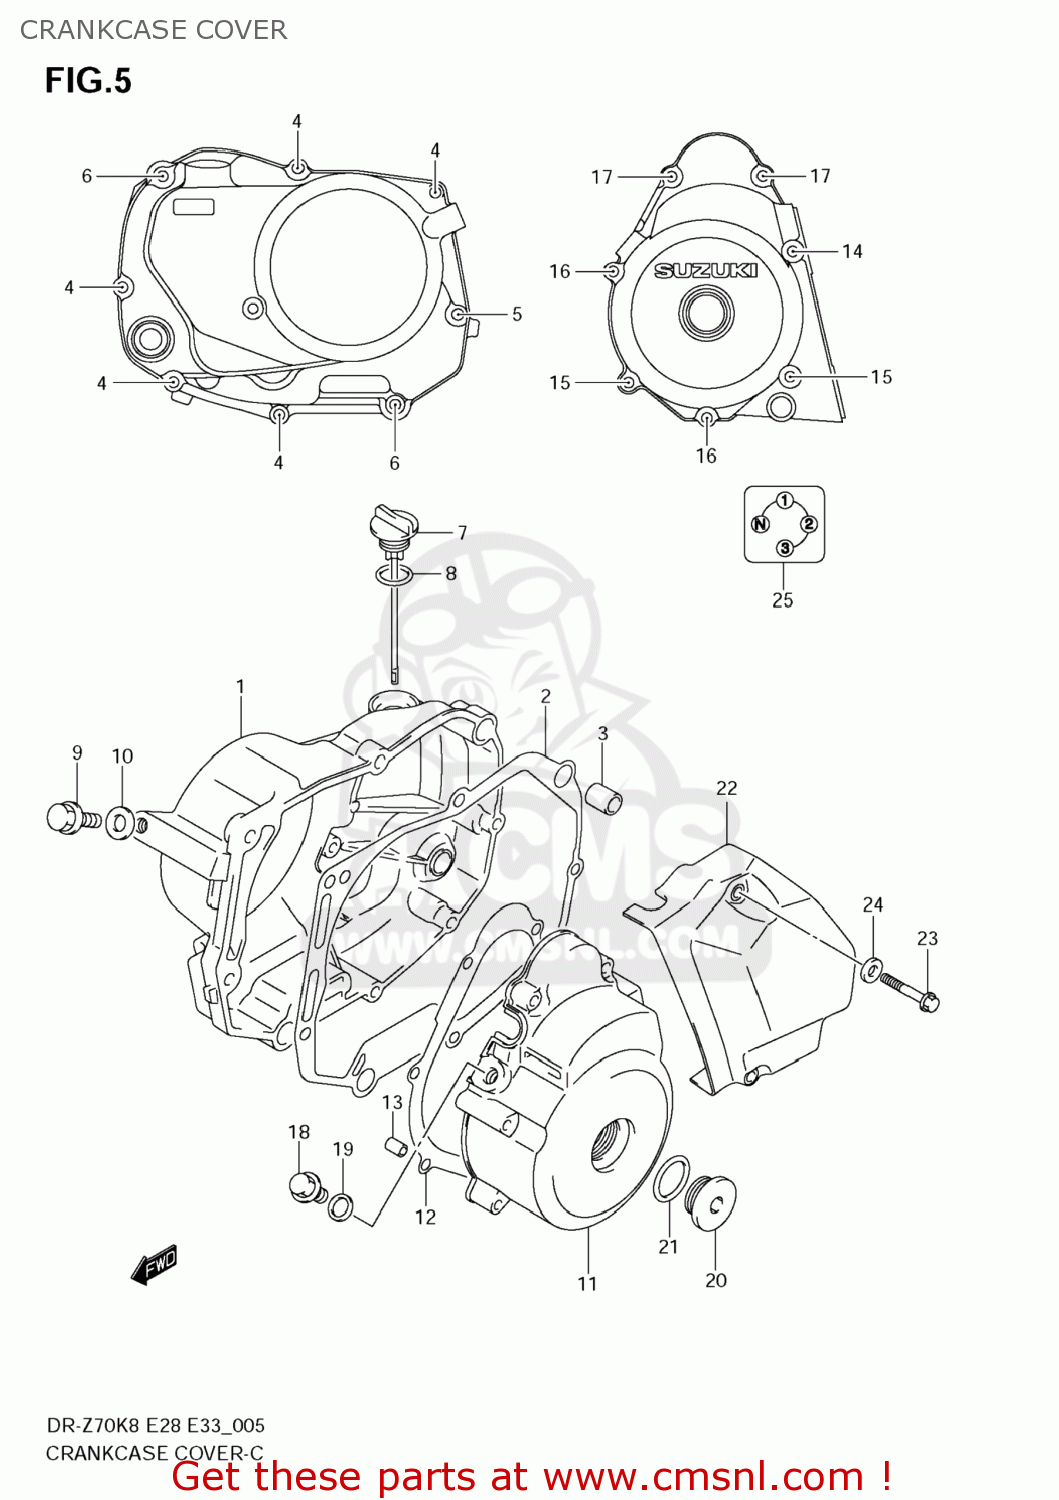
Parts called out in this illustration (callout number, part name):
1	COVER,CLUTCH
2	GASKET,CLUTCH COVER (NAS)
3	PIN
4	BOLT
5	BOLT
6	BOLT
7	GAUGE,OIL LEVEL
8	O RING(D:3.2,ID:15.8)
9	BOLT
10	GASKET(8.2X14X1).6 (NAS)
11	COVER,MAGNETO
12	GASKET,MAGNETO COVER (NAS)
13	PIN
14	BOLT
15	BOLT
16	BOLT
17	BOLT
18	PLUG(12X10)
19	GASKET(12.1X16.2X3.7) (NAS)
20	PLUG(26X9)
21	O RING(D:3.1,ID:22.7)
22	COVER,ENGINE SPROCKET
23	BOLT
24	WASHER
25	LABEL,GEAR SHIFT PATTERN
